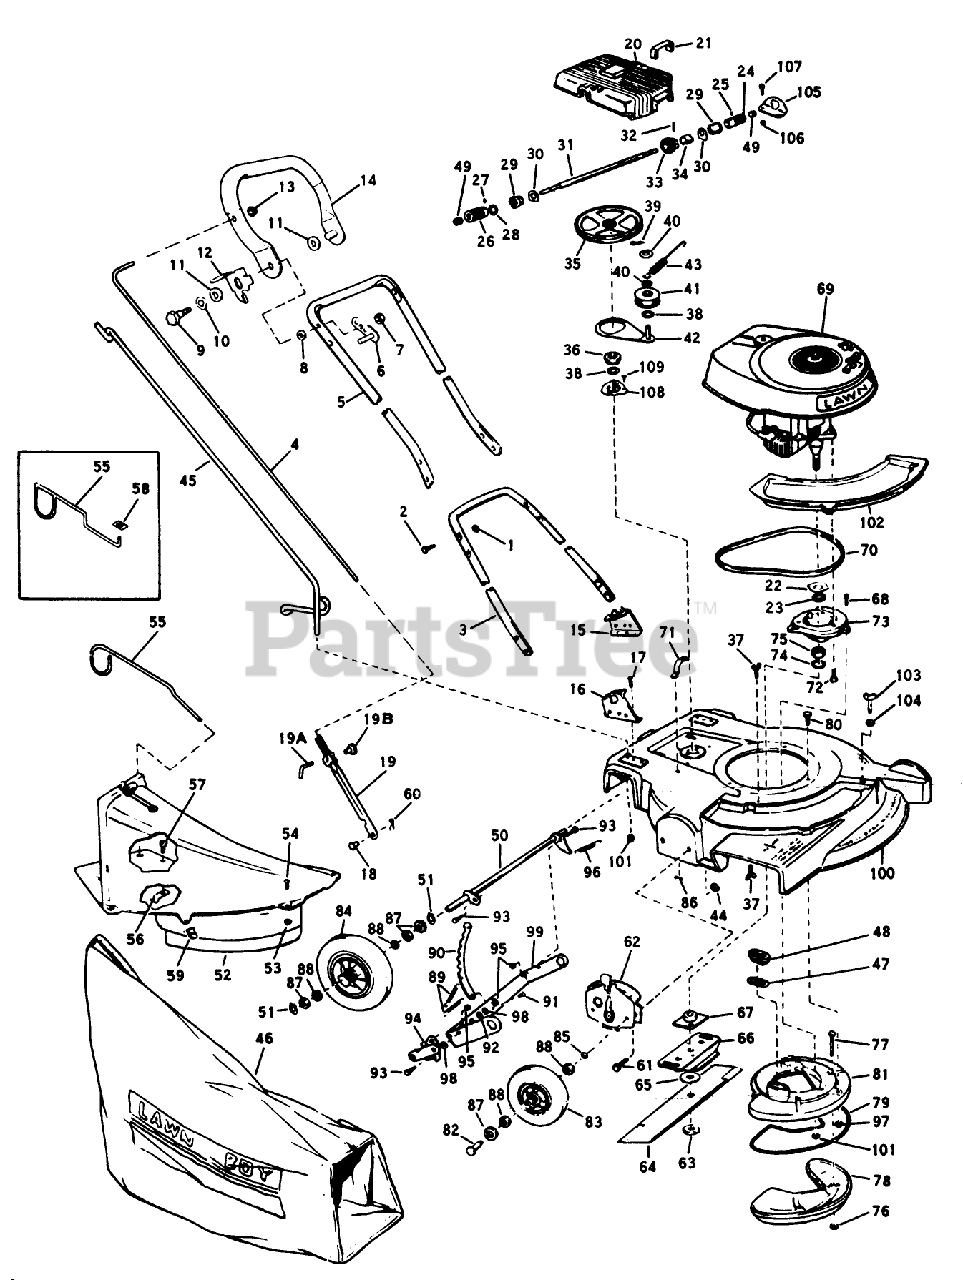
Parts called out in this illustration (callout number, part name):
11	WASHER M
17	SCREW S
35	PULLEY&OILER FELT (13)
46	89802 LB WHOLE GOODS
47	GASKET S
49	GREASE PLUG
51	RETAINING RING
52	Chute Skirt Assembly (Includes Hardware)
59	SPEED NUT ARDEN
63	NUT-BLADE
67	PLATE AND COLLAR ASM
76	LOCKNUT E
82	BOLT WHEEL
85	WASHER WROUGHT
93	BOLT RB&W
95	STOP NUT
98	WASHER S
